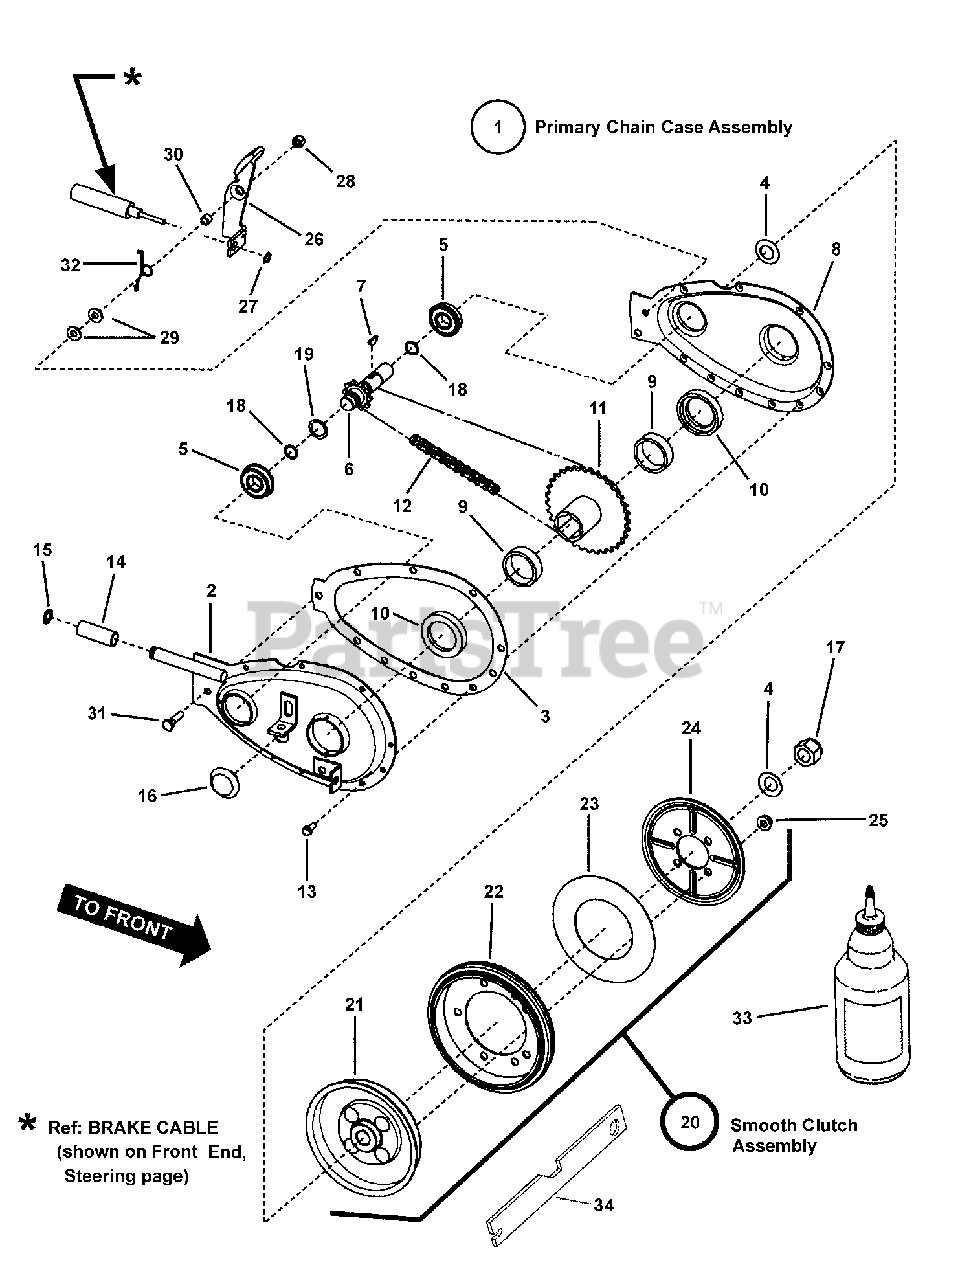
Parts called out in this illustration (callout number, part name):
1	ASSEMBLY, Primary Chain Case
2	WELDMENT, Primary Chain Case Half, Right Hand
3	GASKET, Primary Chain Case
4	WASHER, 5/8" Belleville
5	BEARING, .625 x 1.37 x .435
6	WELDMENT, Sprocket & Shaft
7	KEY,#5 Woodruff
8	PRIMARY CHAIN CASE HALF, Left Hand
9	BEARING, Needle 1.355" ID x 1.6245" OD x .5" Wide
10	THRUST WASHER, Nylon
11	WELDMENT, Hub & Sprocket
12	CHAIN, 46 Pitch (#35 Endless)
13	SCREW, 10-24 x 1/2" Hex Washer Self-Tap
14	ROLLER, 1-3/8 Long
15	RING, 1/2" External Retaining (Heavy Duty)
16	PLUG, 3/4" Cup Insert
17	NUT, 5/8-18 Hex Nyloc
18	O-RING, 1/2 x 5/8"
19	WASHER, Shim .625 x .875
20	ASSEMBLY, Smooth Clutch (non-asbestos)
21	HUB, Driven Disc (assembly)
22	DISC, Driven (Smooth-start, rubber tire bonded to rim with inner liner)
23	THRUST WASHER
24	PLATE, Drive Disc
25	NUT, 5/16-24 Hex Flange Lock
26	ASSEMBLY, Brake Lever (Includes brake pad & rivet)
27	RING, 3/8" External Retaining
28	NUT, 1/4-28 Hex Top Lock
29	WASHER, .28 x .63 x .06 Flat, GR 5
30	* SPACER, Brake Arm Pivot (.418/.403 long)
31	SCREW, 1/4-28 x 1" Hex Head Cap, (Washer Face) GR 5
32	* SPRING, Torsional Brake Return
33	GREASE, Transmission (Use 2 oz. Maximum)
34	TOOL, Smooth Start Clutch (Recommended for Rubber Disc replacement and Drive Disc adjustment)
